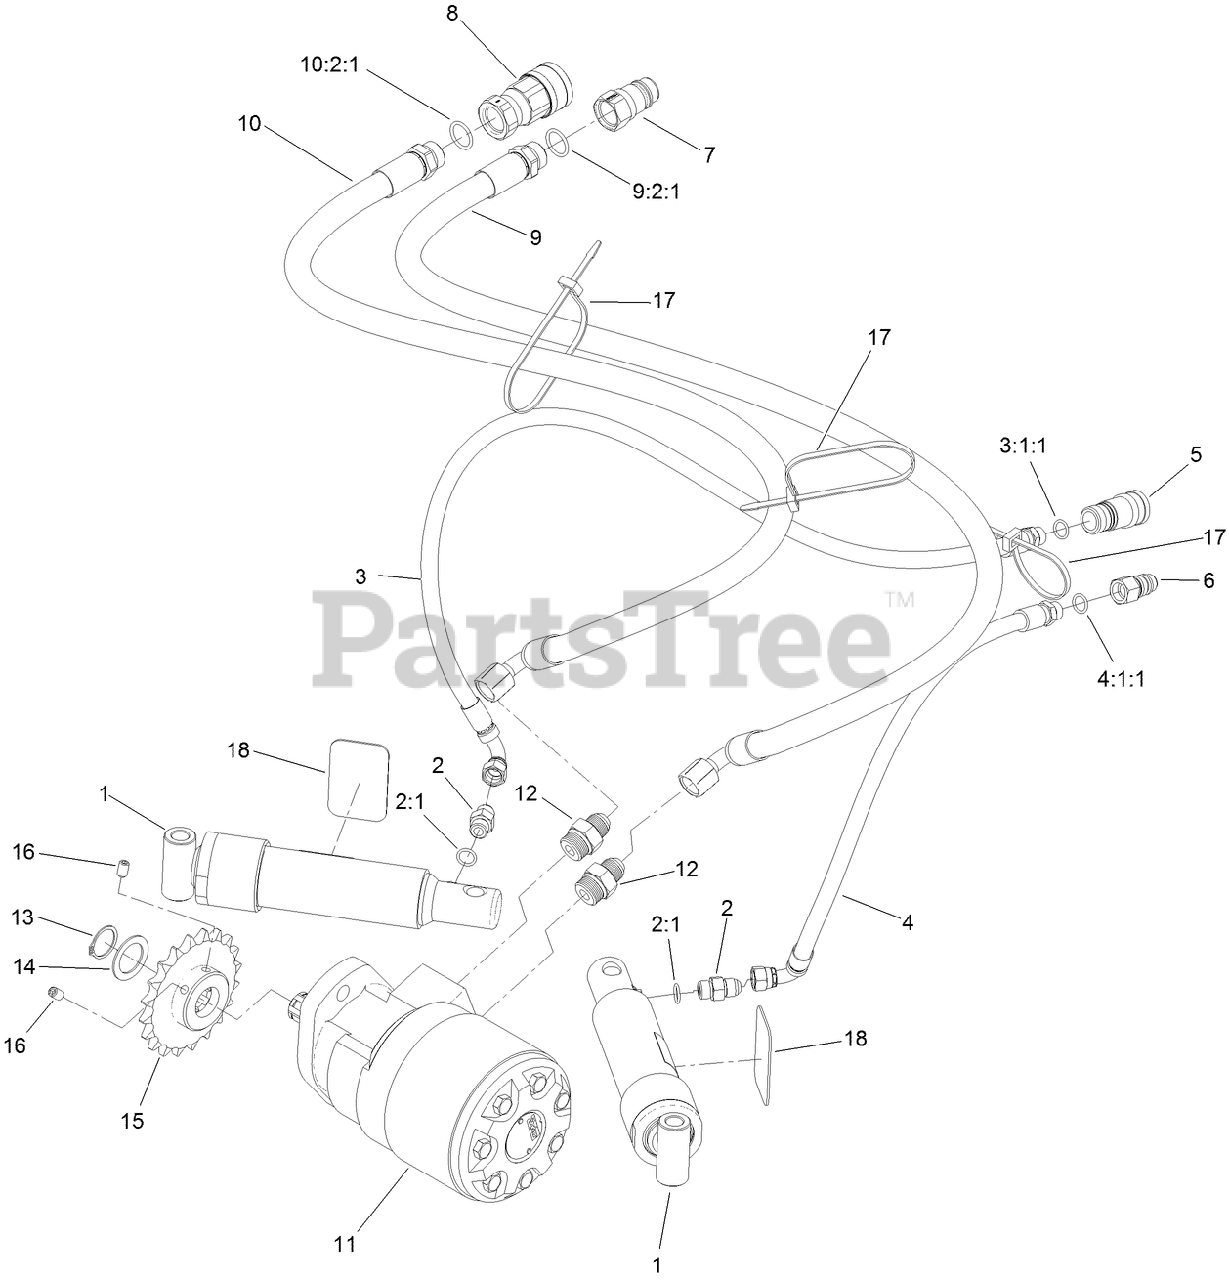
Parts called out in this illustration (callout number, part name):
1	CYLINDER-RAM
2	FITTING-STRAIGHT
2:1	O-RING
3	HOSE ASM
3:1:1	O-RING
4	HOSE ASM
4:1:1	O-RING
5	COUPLER-DISCONNECT, QUICK
6	NIPPLE-DISCONNECT, QUICK
7	DISCONNECT-QUICK , MALE
8	DISCONNECT-QUICK, FEMALE
9	HYD HOSE ASM
9:2:1	O-RING
10	HYD HOSE ASM
10:2:1	O-RING
11	MOTOR-HYDRAULIC
12	FITTING-STRAIGHT
13	RING-RETAINING
14	WASHER-THRUST
15	SPROCKET-CHAIN
16	SETSCREW-HSH
17	TIE-CABLE
